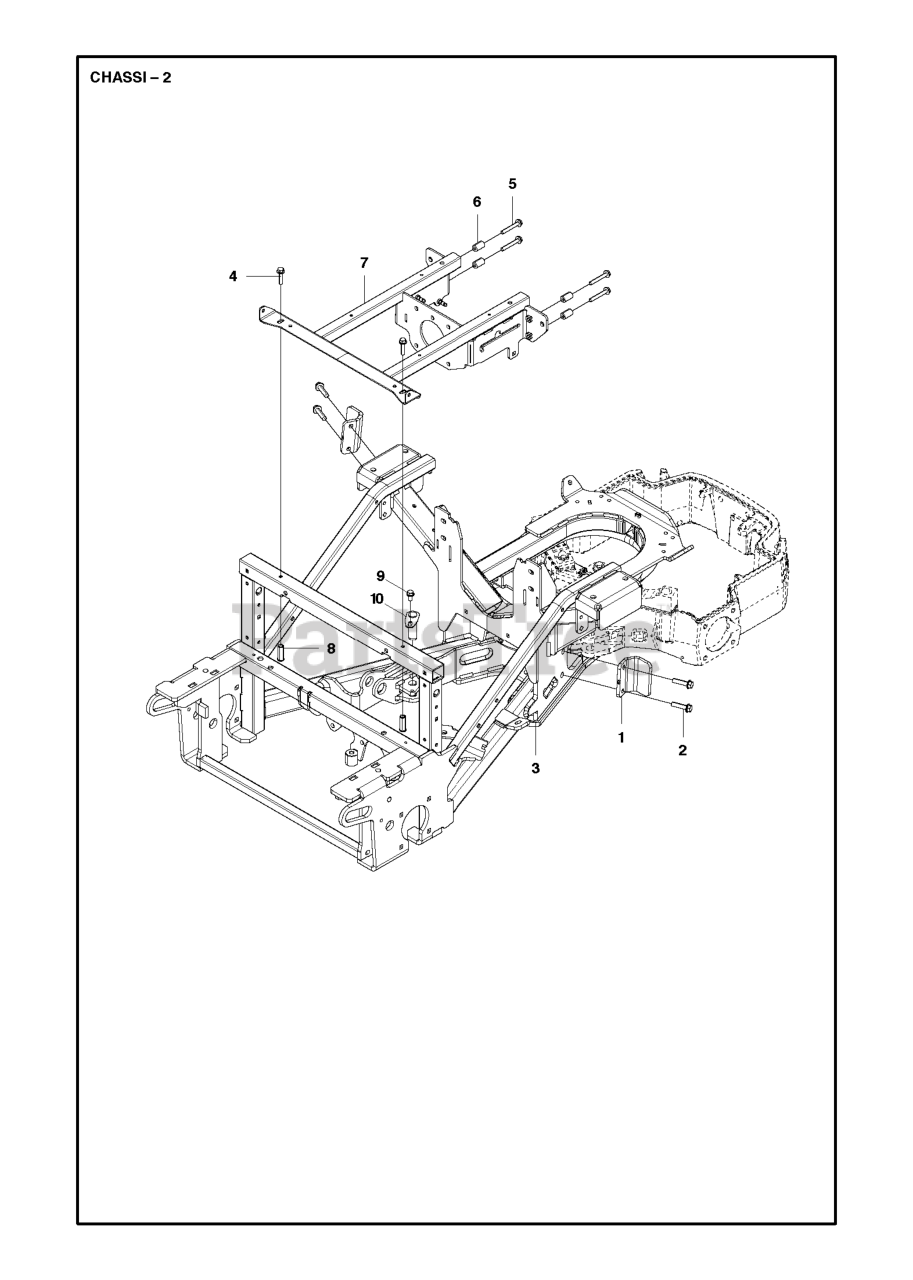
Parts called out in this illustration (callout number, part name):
4	SCREW EHHFM
5	SCREW EHHFM
9	BOLT
